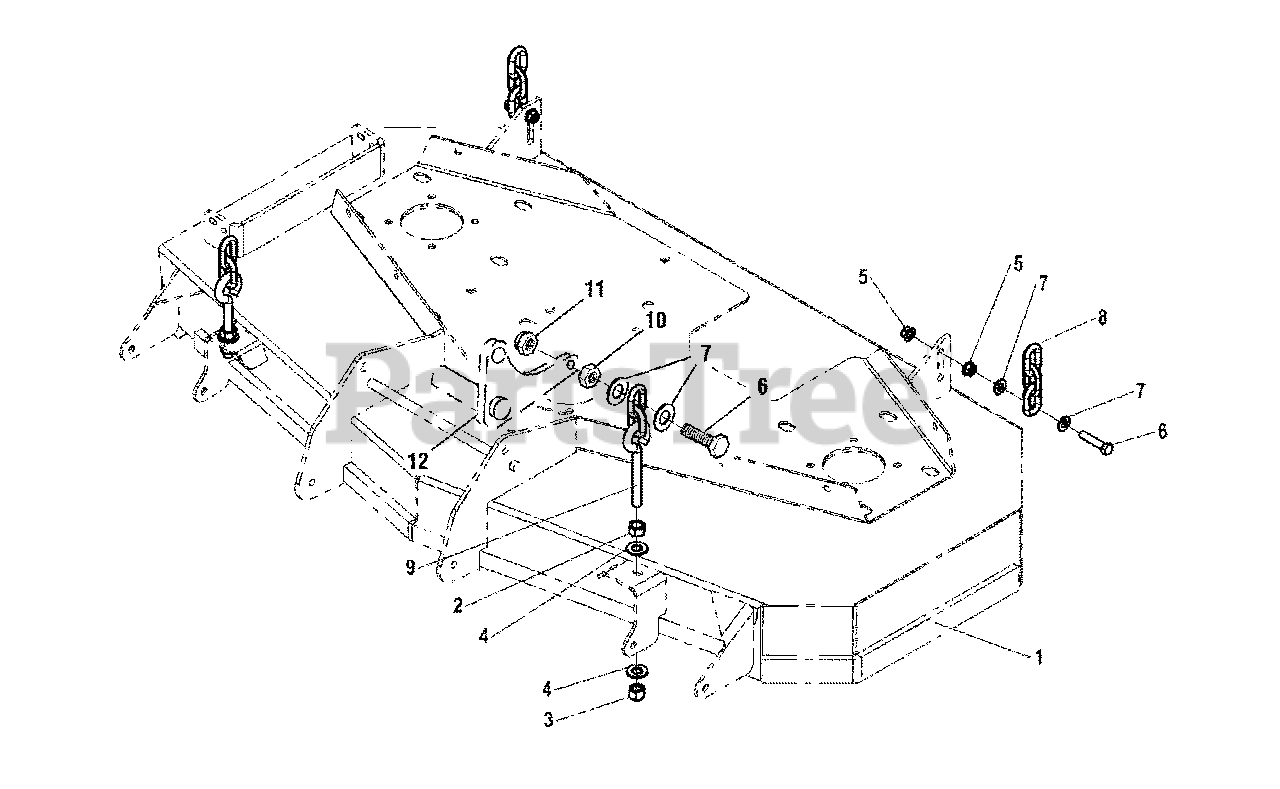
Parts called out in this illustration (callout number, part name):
1	MOWER DECK
2	NUT, 1/2-13 HEX
3	NUT, 1/2-13 HEX NYLOCK FLANGE
4	WASHER, 1/2" SAE
5	NUT, 3/8-16 HEX SERRATED FLANGE
6	BOLT, 3/8-16 X 1-3/4" GD5
7	WASHER, 3/8" SAE
8	CHAIN, 5/16" GD30, 3 LINKS
9	HANGER, FRONT DECK - 2 LINK, 5.5" EB
10	NUT, 3/8-16 HEX JAM
11	NUT, 3/8-16 HEX NYLOCK FLANGE
12	DECK LIFT PIVOT
